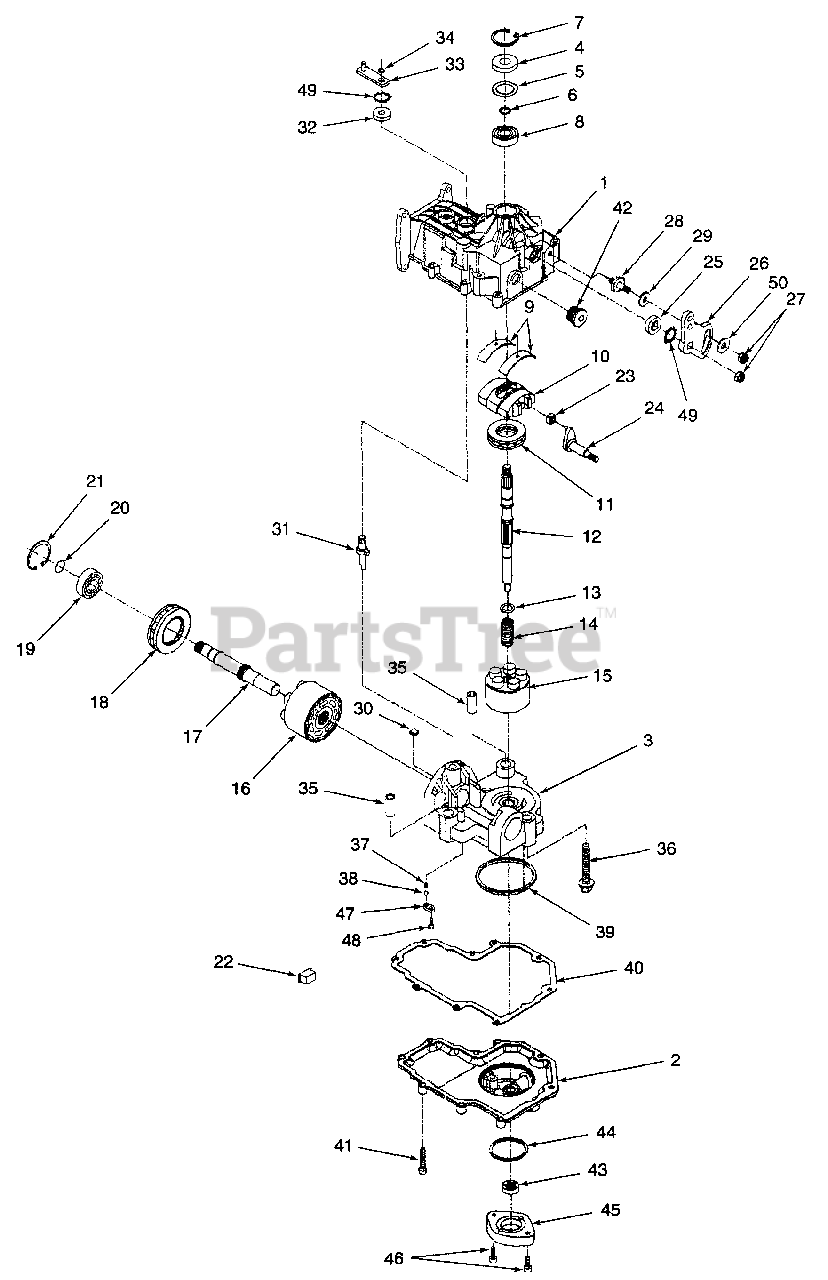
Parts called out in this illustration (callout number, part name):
1	Housing Ass'y, Upper
2	Housing, Lower
3	Center Section Assembly
6	Ring, Wire Retaining
7	Ring, Retaining
8	Bearing, Ball
9	Bearing, Cradle
10	Swashplate, Variable
11	Bearing, Thrust
12	Shaft, Input
13	Washer, Block Thrust
14	Spring, Block
15	Block Assembly, Cylinder
16	Block Assembly, Cylinder
17	Shaft, Output (Motor)
18	Bearing, Thrust
19	Bearing, Ball
20	Ring, Wire Retaining
21	Ring, Retaining
22	Retainer, Motor Bearing
23	Guide, Slot
24	Arm, Trunnion
26	Arm, Control
27	Nut, Hex Lock, 5/16-24
28	Stud, Short, 5/16-24
29	Puck, Friction
30	Plate, Bypass
31	Actuator, Bypass
32	Seal, Lip
33	Arm, Bypass
34	Ring, Retaining
37	Spring, Charge Relief
41	Screw, Self Tapping
43	Gerotor Assembly
45	Cover, Gerotor
47	Plate, Relief
49	Ring, Retaining
